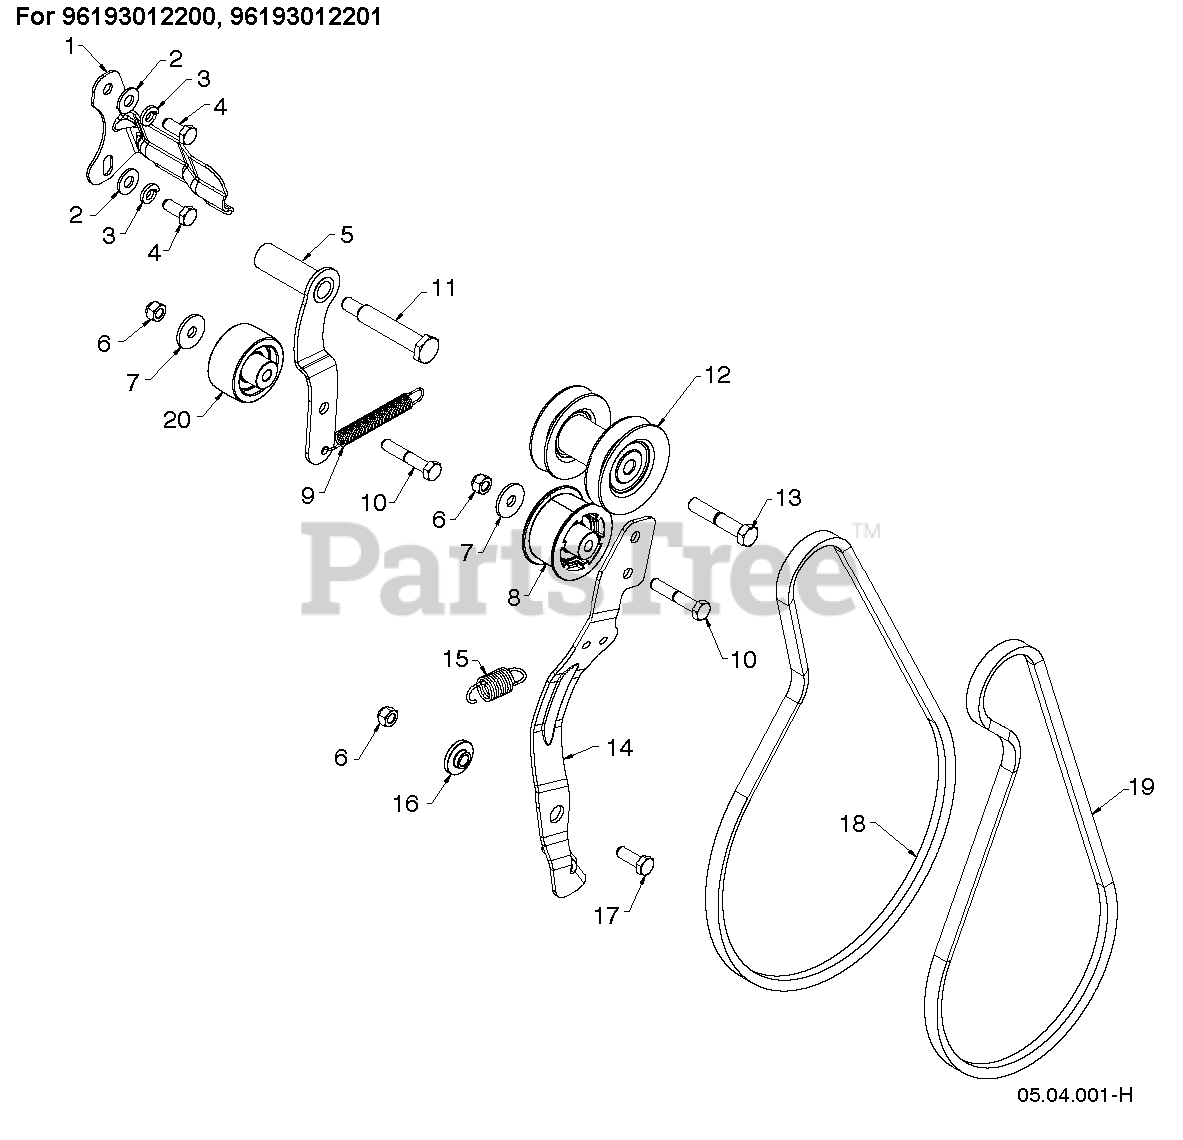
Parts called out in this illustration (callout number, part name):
1	BELT KEEPER BRACKET
2	WASHER M
3	WASHER.LOCK.HVY.HLCL.SPR.5/16
4	SCREW 5/16-24 X .75 GR5
5	ARM IDLER DRIVE WELDMENT_HOT
6	NUT.71038.31-18.HEX.NYLOCK
7	STEEL WASHER
8	PULLEY,IDLER,2.00 W SPA
9	SPRING RETURN IDLER ARM
10	BOLT, HEX 5/16-18X1-3/4
11	BOLT 5/16-24X2.25 HEX HEAD SHO
12	PULLEY.ASM.IMPELLER/DRIVE
13	BOLT.HD.HEAD.3/8-24X2.50 (2 2)
13	BOLT.ENGINE.PULLEY
14	ARM.IDLER.AUTO-PH.676
14	BRACKET ARM.IDLER.IMPELLER ARM
15	SPRING RETURN, IDLER ARM, IMPE
16	BUSHING.BRAKE.ARM
17	BOLT
18	BELT.DRIVE.SNOW.DUAL
19	LOW CRANK IMPELLER BELT
20	PULLEY.IDLER.FLANG.2.O/SPACER
